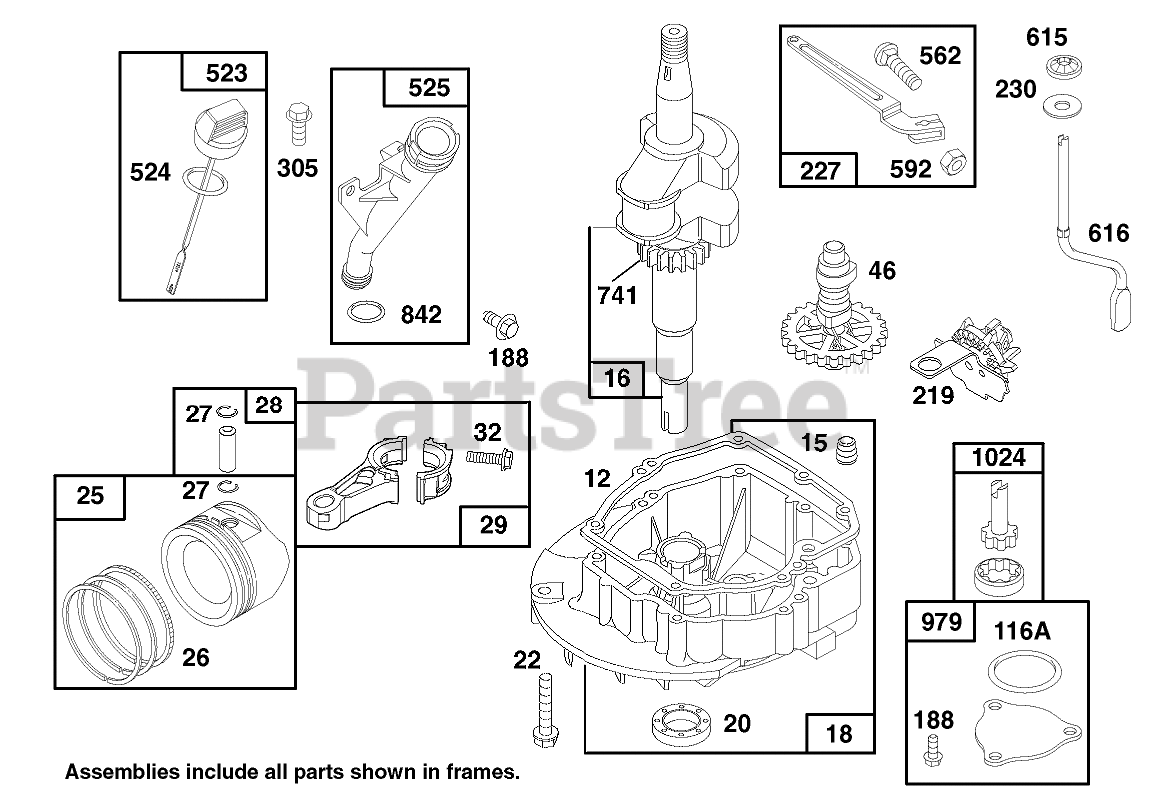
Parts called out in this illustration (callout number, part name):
1	CYLINDER ASSEMBLY
12	ENGINE BASE GASKET
15	PLUG - PIPE
16	CRANKSHAFT
18	ENGINE SUMP
20	SEAL-OIL
22	SCREW - ENGINE BASE
25	STD PISTON ASSEMBLY
26	STD RING SET
27	PISTON PIN LOCK
28	PIN ASM - PISTON
29	STD PISTON ASSEMBLY
32	SCREW - CONNECTING ROD
46	CAM GEAR
116A	O RING SEAL
188	SCREW - HEX HEAD
188	SCREW - SEM
219	GOVERNOR/OIL SLINGER
227	GOVERNOR LEVER ASSEMBLY
230	WASHER
305	SCREW - HEX HEAD
523	DIPSTICK-OIL
524	O-RING
525	OIL FILLER TUBE
562	GOVERNOR LEVER BOLT
592	HEX NUT
615	FASTENER
616	GOVERNOR CRANK
741	TIMING GEAR
842	O-RING
979	OIL PUMP COVER
1024	OIL PUMP
